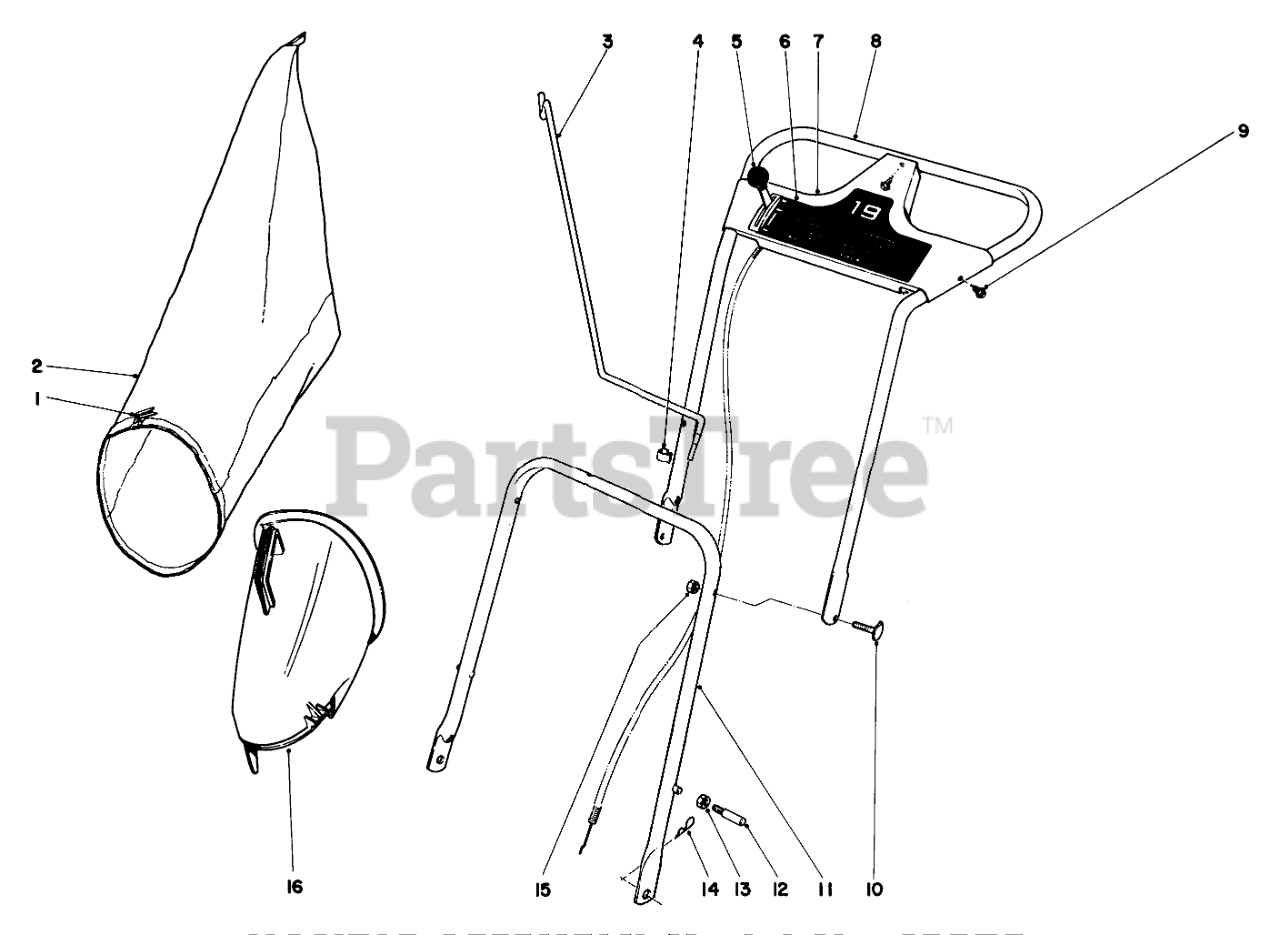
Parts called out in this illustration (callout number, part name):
1	BAG CORD FASTENER
2	Grass Bag Kit
3	Bag Hanger Rod
4	CONTROL WIRE CLIP
5	Throttle Control
6	Decal, Escutcheon Plate
7	Escutcheon Plate
8	Upper Handle
9	SCREW-HWHTF
10	1-1/4 LG HANDLE SCREW
11	Lower Handle
12	Handle Pin
13	Nut
14	PIN-COTTER, HAIR
15	Nut
16	Bag Attachment
